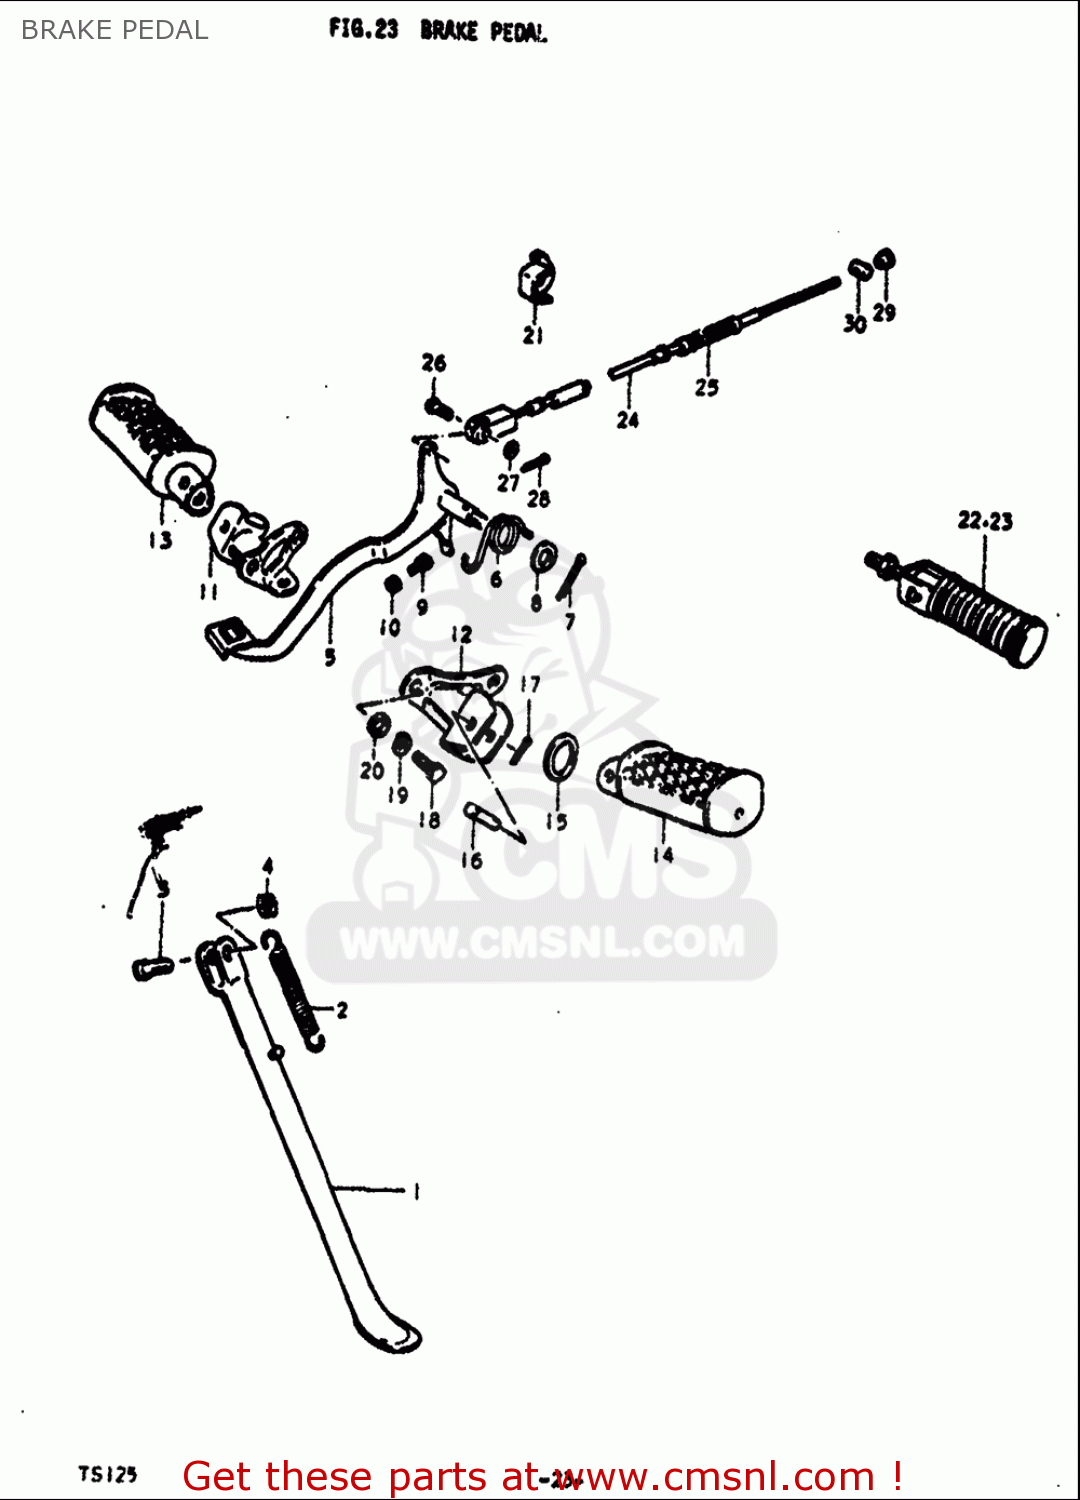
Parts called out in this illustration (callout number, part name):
2	SPRING
3	BOLT(10X30)
4	NUT
6	SPRING
7	PIN
8	WASHER(10.3X25X1.5
9	BOLT
10	NUT
15	WASHER(22.5X38X1)
16	PIN
17	PIN
18	BOLT
19	WASHER,LOCK
20	WASHER
23	FOOTREST ASSEMBLY,REAR
24	CABLE,RR BRAKE
25	SEAL,DUST
26	PIN
27	WASHER
28	PIN
29	NUT
30	PIN(11X18)
